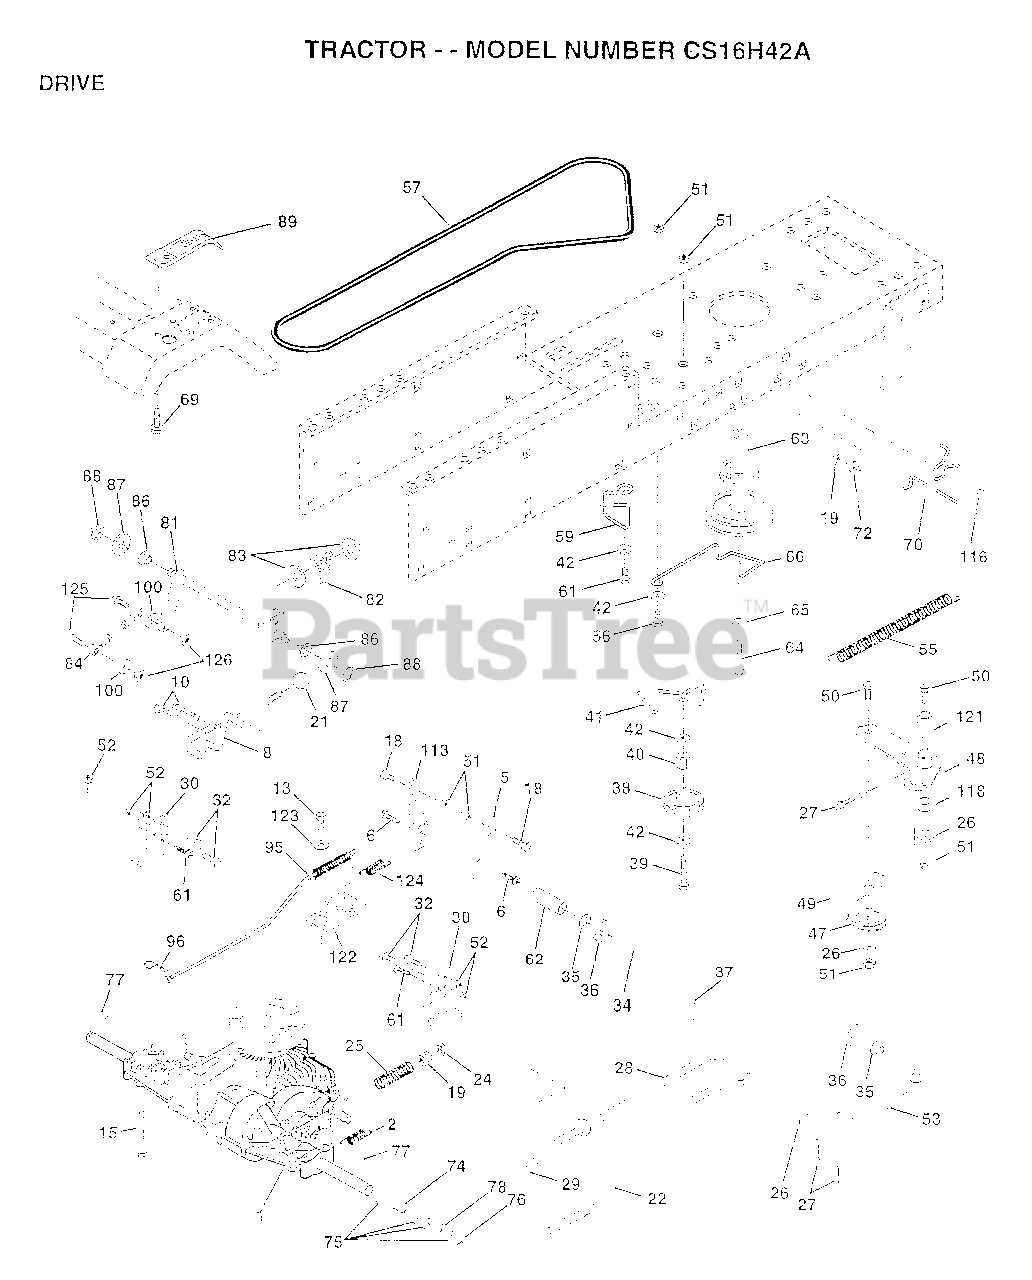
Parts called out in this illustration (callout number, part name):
1	TRANSAXLE, PEERLESS
2	SPRING.BRAKE.RETU
5	STRAP TORQUE
6	SCREW
8	ROD SHIFT FEND LT
10	PIN COTTER 1/8
13	BOLT.1/4-28.W/PAT
15	BOLT.HX.FLG.5/16
18	BOLT
19	NUT
21	KNOB DLX BLK/BLK
22	BRAKE ROD
24	NUT
25	SPRING ROD LT
26	WASHER
27	COTTER PIN
28	ROD.BRAKE.PARK.LT
29	PLUNGER CAP T
30	TRANSAXLE MTG BKT
32	BOLT
34	SHAFT ASM-PEDAL F
35	NYLON BEARING
36	WASHER LT
38	PULLEY.IDLER.FLAT
39	BOLT
40	SPACER T
42	WASHER
48	BELLCRANK ASM
49	RETAIN BELT
53	"LINK, CLUTCH T"
55	"SPRING, RETURN LT"
57	"V-BELT,GRD DRIVE"
59	KEEPER BELT CNTSP
61	SCREW
62	PEDAL COVER T
63	PULLEY.ENGINE
64	BOLT
65	LOCKWASHER
66	KEEPER-BELT
69	SCREW HEXWSH H-L
70	KEEPER BELT ENG
72	CONFLICT W/PART #
74	"SPACER AXLE,PVST"
75	WASHER
76	E-RING LT
77	SQUARE KEY
78	WASHER
81	SHAFT ASM CROSS
82	"SPRING,TORSION"
83	WASHER
84	"ROD TIE, PVST 20"""
86	BUSHING
87	WASHER D
88	KLIP RING
95	ROAD ASM BYPASS
96	RETAINER M
100	WASHER M
113	"STRAP,TORQUE"
116	BOLT RDHD 3/8-16
118	SPACER-BELLCRANK
121	NYLINER-CLUTCHING
122	"PLATE-BYPASS,PVST"
123	WASHER
124	SPRING RETURN
